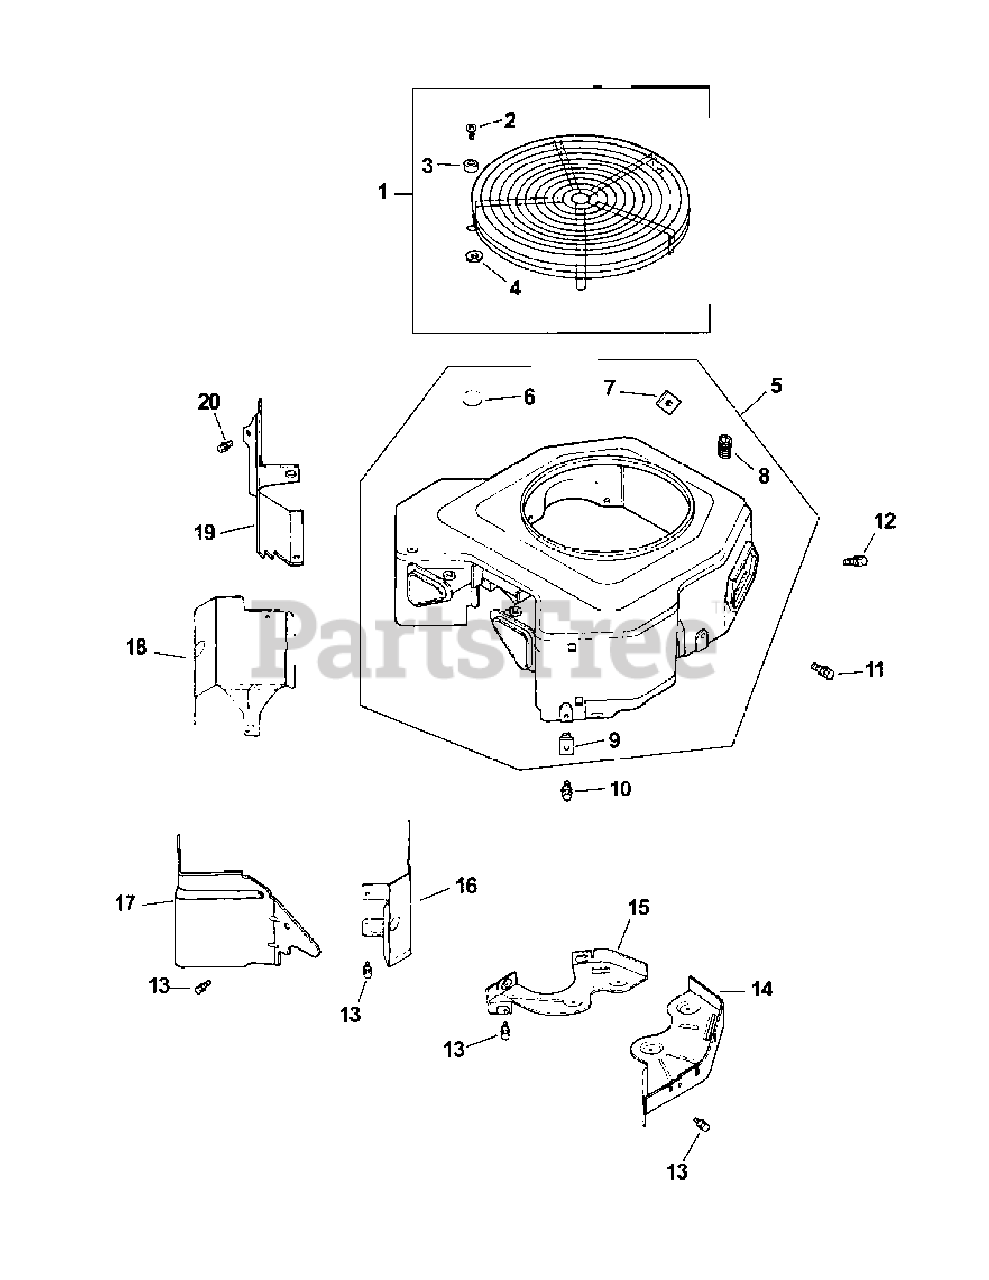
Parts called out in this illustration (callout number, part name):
2	Pan Head Screw
3	Spacer
5	Blower Housing
6	Button Plug (9/16")
10	Hex Flange Screw (M5 x .8 x 20)
11	Hex Flange Screw (M5 x .8 x 16)
12	Hex Flange Screw (M5 x .8 x 16)
13	Hex Flange Screw (M6 x 1.0 x 16)
14	Backing Plate #2 Side
15	Backing Plate #1 Side
16	Cylinder Barrel Baffle # 2 Side
17	Valley Baffle # 2 Side
18	Cylinder Barrel Baffle # 1 Side
19	Valley Baffle # 1 Side
20	Hex Flange Screw (M5 x .8 x 10)
